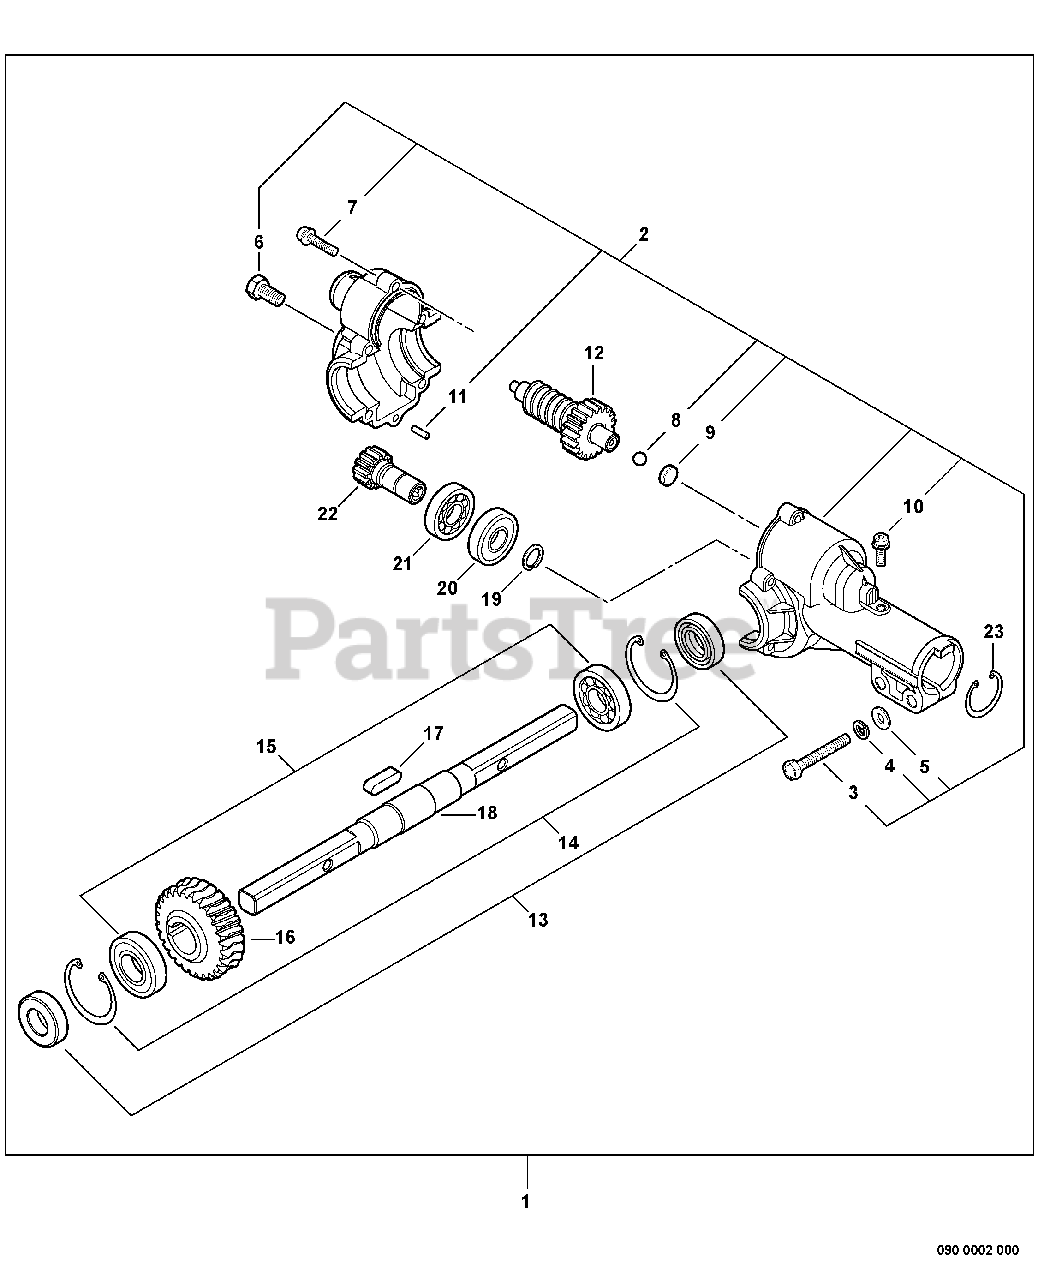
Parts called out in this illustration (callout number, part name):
1	GEAR CASE ASSY
2	GEAR CASE ASSY
3	BOLT - 6X25
4	LOCKWASHER - 6
5	WASHER - 6
6	BOLT - 8X8
7	SCREW - 4X25
8	BALL, STEEL
9	WASHER - 3
10	SCREW - 5X14
11	PIN - LOCATING
12	GEAR - WORM
13	SEAL, OIL - 17
14	RING, RETAINING - 30
15	BEARING, BALL - 6903
16	WHEEL, WORM
18	SHAFT, WORM GEAR
19	RING, RETAINING - 9
20	BEARING, BALL - 609
21	BEARING, BALL - 609
22	GEAR - DRIVE
23	RING, RETAINING - 25
